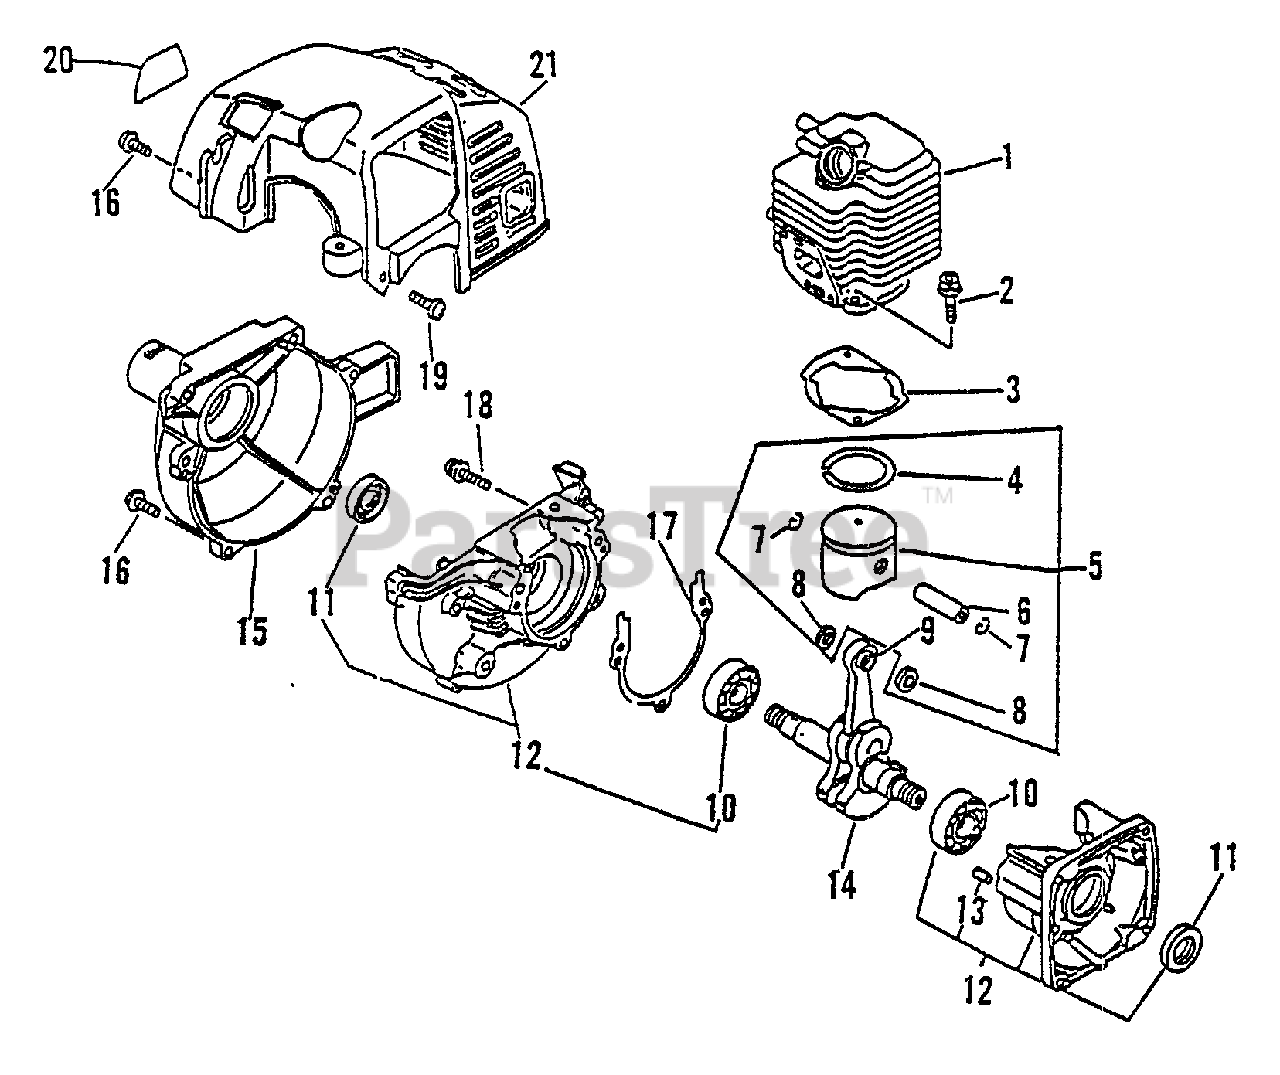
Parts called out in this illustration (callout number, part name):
1	CYLINDER
2	SCREW - 5X22
3	GASKET, CYLINDER
4	RING, PISTON
5	PISTON KIT
6	PIN, PISTON
7	RING, RETAINING
8	SPACER, PISTON
9	BEARING, NEEDLE
10	BEARING, BALL - 6201
11	SEAL, OIL
12	CRANKCASE KIT
13	PIN - LOCATING
14	CRANKSHAFT ASSY
15	CASE, FAN
16	SCREW - 4X16
17	GASKET, CRANKCASE
18	SCREW - 5X28
19	SCREW - 4X12
20	LABEL - MODEL LST-2100
21	COVER, ENGINE
